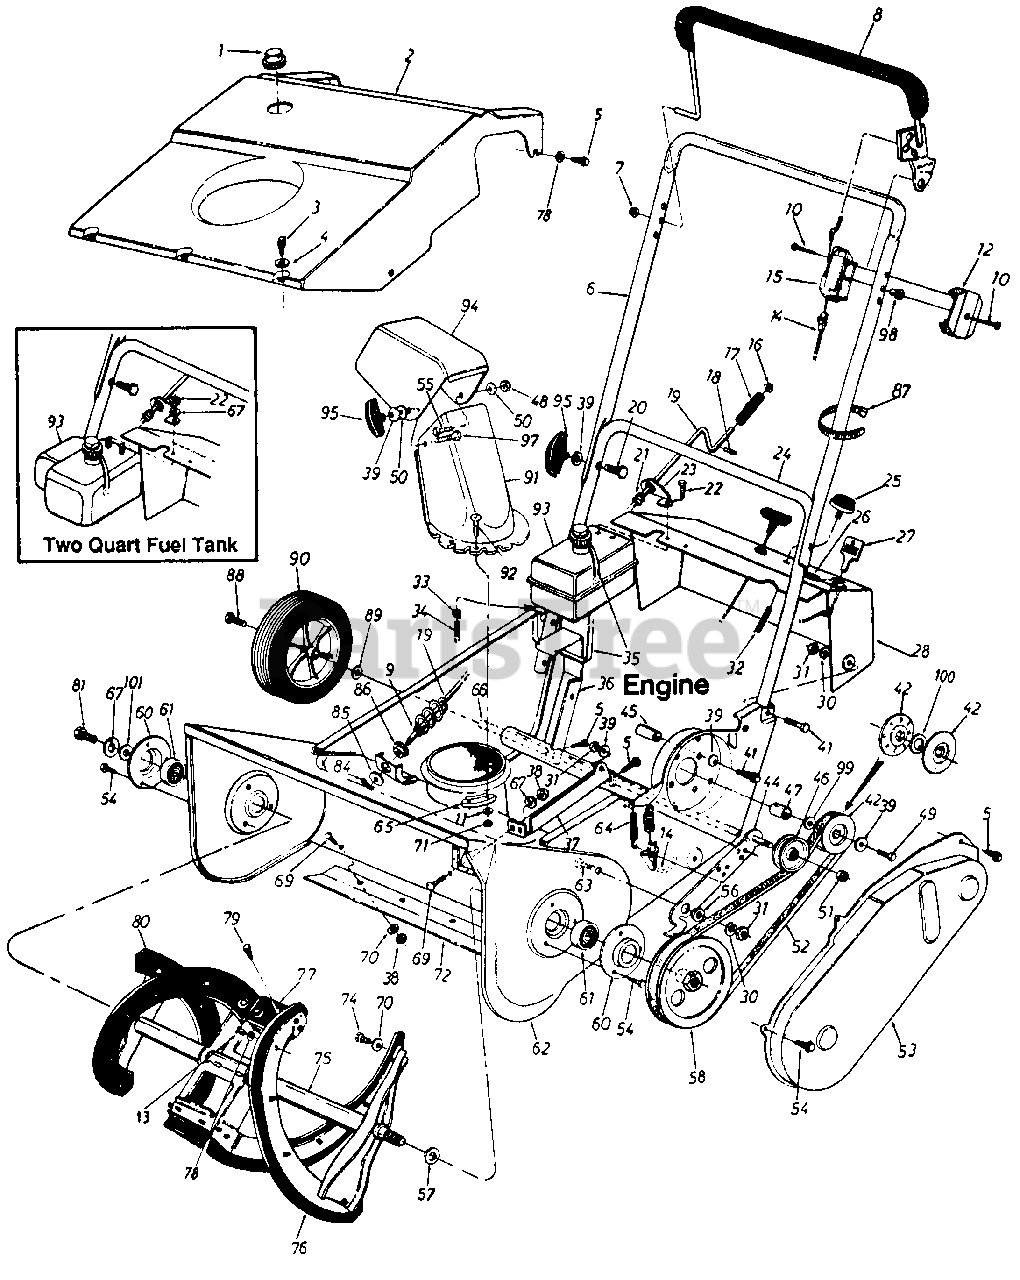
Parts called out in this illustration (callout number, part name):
1	Gas Tank Cap
2	21" Shroud
3	Hex B-Tap Scr. #10 x .38"
4	Spr.-Wash. .206" I.D. x .448"
5	Hex L-Wash. Hd. AB-Tap 1/4 x .62" Lg.
8	Control Handle Ass'y.-L.H.
9	Fl-Wash. .385" 1 .D. x .62"
10	Truss Mach. Hi-B Tap Scr. #12 x 1.5" Lg.
11	Fl-Wash. .281" I.D. x .5" O.D.
12	Control Panel Half
13	Pop Rivet .188" Dia.
14	Clutch Cable 35" Lg.
15	Control Panel Half
16	Push Cap 3/8" Rod
17	Knob-3/8" Dia. Hole
18	Roll Pin 1/8" Dia. x .63" Lg.
19	Chute CrankAss'y.
20	Curved Carriage Bolt 5/16-18 x 1.75" Lg.
21	Chute Crank Grommet
22	Hex AB-Tap Scr. 1/4 x .75" Lg.
23	Upper Chute Crank Brkt.
26	Plastic Plug
27	Plastic Key
31	Hex Nut 5/16-18 Thd.
32	Primer Hose-11H Lg.
33	Hose Clamp-1/2" Dia.
34	Gas Line-12" Lg.
35	CableTic 17.75" Lg.
38	Hex Jam Nut 1/4-20 Thd.
39	Bell-Wash. .345" I.D. x .88"
41	Hex Bolt 5/16-18 x 1.5" Lg.
42	3/8" "V"-Pulley Half .625" I.D. x 6.0" O.D.
46	Fl-Idler w/Flanges 2.12" O.D.
47	Spacer .635" I.D. x .89" O.D. x .57"
48	Hex L-Nut 5/16-18 Thd.
49	Hex Bolt 5/16-24 x .75" Lg.
50	Fl-Wash. .344" I.D. x 1.25"
51	Hex Patch L-Nut 3/8-24 Thd.
52	"V"-Belt
54	Hex B-Tap Scr. 1/4" x .38" Lg.
55	Carriage Bolt 5/16-18 x .75"
56	Shld. Spacer .50" Dia. x .27"
57	Fl-Wash. .510" I.D. x 1.0" O.D.
58	3/8" "V"-Pulley 1/2-20 L.H. x 6"
64	Extension Spring 1.12" Lg.
65	Chute Flange Keeper
66	Wheel Axle 1/2" O.D. x 20.6" Lg.
67	L-Wash. 1/4" I.D.
69	Carriage Bolt 1/4-20 x .50"
70	Fl-Wash. .281" I.D. x .73"
71	Hex L-Nut 1/4-20 Thd.
72	Shave Plate
74	Hex Wash. B-Tap Scr. 1/4 x .62"
76	Rubber Spiral-L.H.
77	Rubber Paddle
78	Fl-Wash. .218" I.D. x .62"
79	Hex Wash. B-Tap Scr. #10 x .62" Lg.
80	Rubber Spiral-R.H.
81	Hex Wash. TT-Tap Cl-Scr. 1/4-20 x .75" Lg.
84	Cotter Pin 3/32" Dia. x .75"
85	Fl-Wash. .406" I.D. x 1.25"
86	Hex Bushing .385" I.D.
87	Cable Tie
88	Hex Tap Scr. 3/8-24 x .5" Lg.
89	Fl-Wash. .510" I.D. x .75"
90	Wheel & Tire Ass'y. 7" x 1.5"
91	Lower Chute
92	Truss Mach. Scr. 1/4-20 x .75"
93	Fuel Tank-One Quart
94	Upper Chute
95	Knob Handle.Ass'y.
97	Carriage Bolt 5/16-18 x 1"
98	Control Disc Pin
99	Fl-Wash. .635" I.D. x 1.04" O.D.
100	Fl-Wash. .635" I.D. x .93" O.D.
101	Fl-Wash. .25" I.D. x .93"
